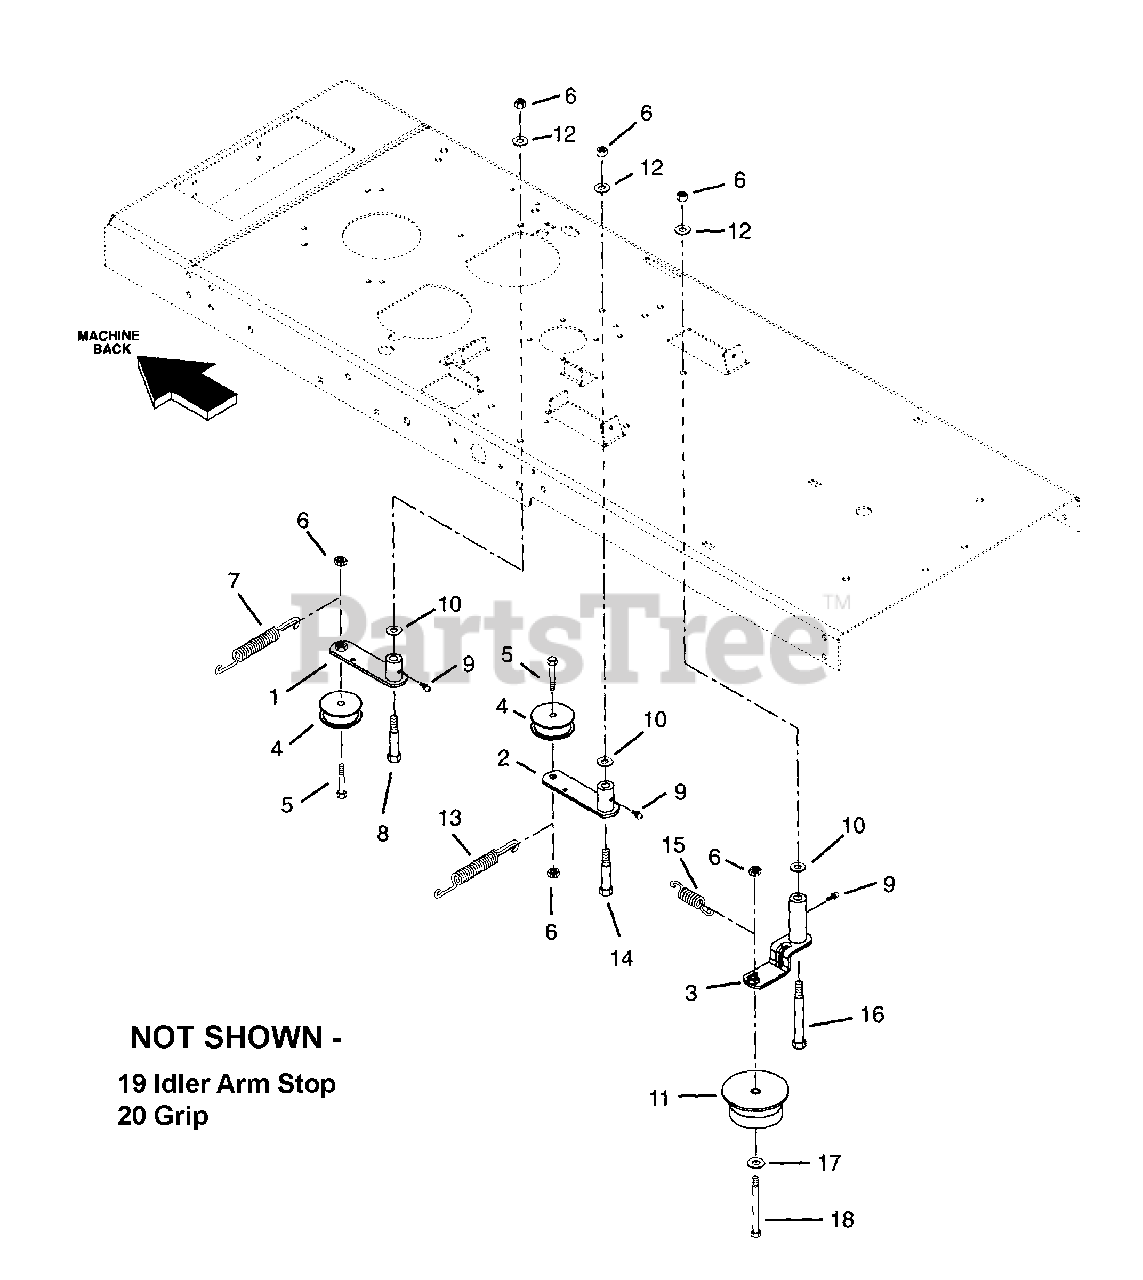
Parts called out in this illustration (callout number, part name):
1	IDLER ARM - TRANS/ENG
2	IDLER ARM CLUTCH/ENG
3	ARM - IDLER PIVOT
3	ARM, IDLER
4	IDLER - 2.25X.87
4	IDLER 3.00 - .75
4	V - IDLER 3.0" - 3L
5	BLT-HEX .38-16X2.00 PL GR5
6	NUT-LK-NYL .375-16 PL
7	SG-TENS
7	SPRING - ENGINE - TRANS.
8	SCREW, SHLDR
9	FTG-LUBE .25-28X.256 YWZC
10	WSHR-FL-STL .520X.827X.062 YZ
11	IDLER FLANGED 3.50
11	IDLER 4.0" DIA
12	WSHR-FL-STL .390X.750X.125 PL
12	@WSHR-FL-STL.406X.812X.065 YWZ
13	SG-TENS
13	SPRING - ENG - JACK
14	SCREW, .50 X 2.0 SHOULDER
15	SPRING, EXT
16	BLT-SHOULDER .50X3.75 LG
16	SHOULDER BOLT .50X3.50
17	WSHR-FL-STL.406X.812X.065PL
18	BLT-HEX .38-16X2.00 PL GR5
18	@BLT-HEX .38-16X2.50 GR5 YWZC
19	IDLER ARM STOP
20	GRIP
